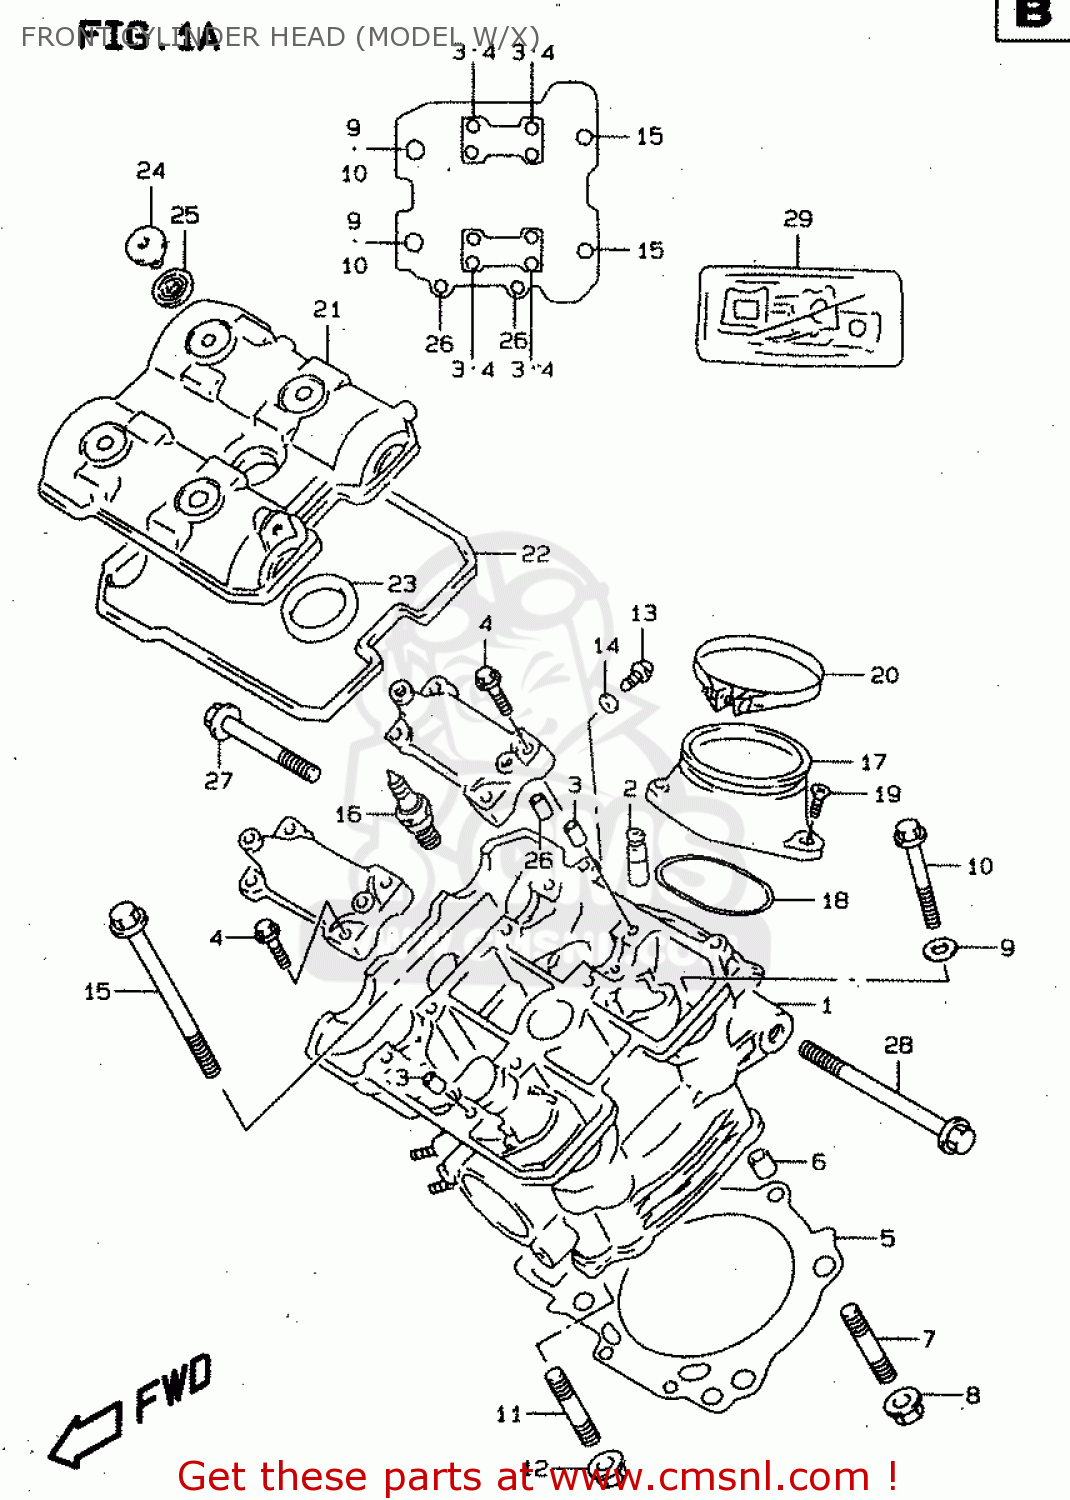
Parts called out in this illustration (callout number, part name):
1	HEAD,CYLINDER
2	GUIDE,VALVE
3	PIN(6.2X8X11)
4	BOLT(6X39)
5	GASKET,CYLINDER HEAD (NAS)
6	PIN
7	BOLT,STUD
8	NUT
9	WASHER(10.5X19X2)
10	BOLT,CYLINDER HEAD(L:175)
11	BOLT,STUD
12	NUT
13	BOLT
14	GASKET
15	BOLT(6X70)
16	PLUG,SPARK(CR8EK)
17	PIPE ASSY,INTAKE
18	O RING(D:2.4,ID:55.6)
19	SCREW
20	CLAMP
21	COVER,CYLINDER HEAD FR
22	GASKET,CYL HEAD COVER NO.1 (NAS)
23	GASKET,CYL HEAD COVER NO.2
24	BOLT(7X17.5)
25	WASHER(10.6X25.5X2.3)
26	PIN(6.2X8X11)
27	BOLT
28	BOLT
29	GASKET SET
